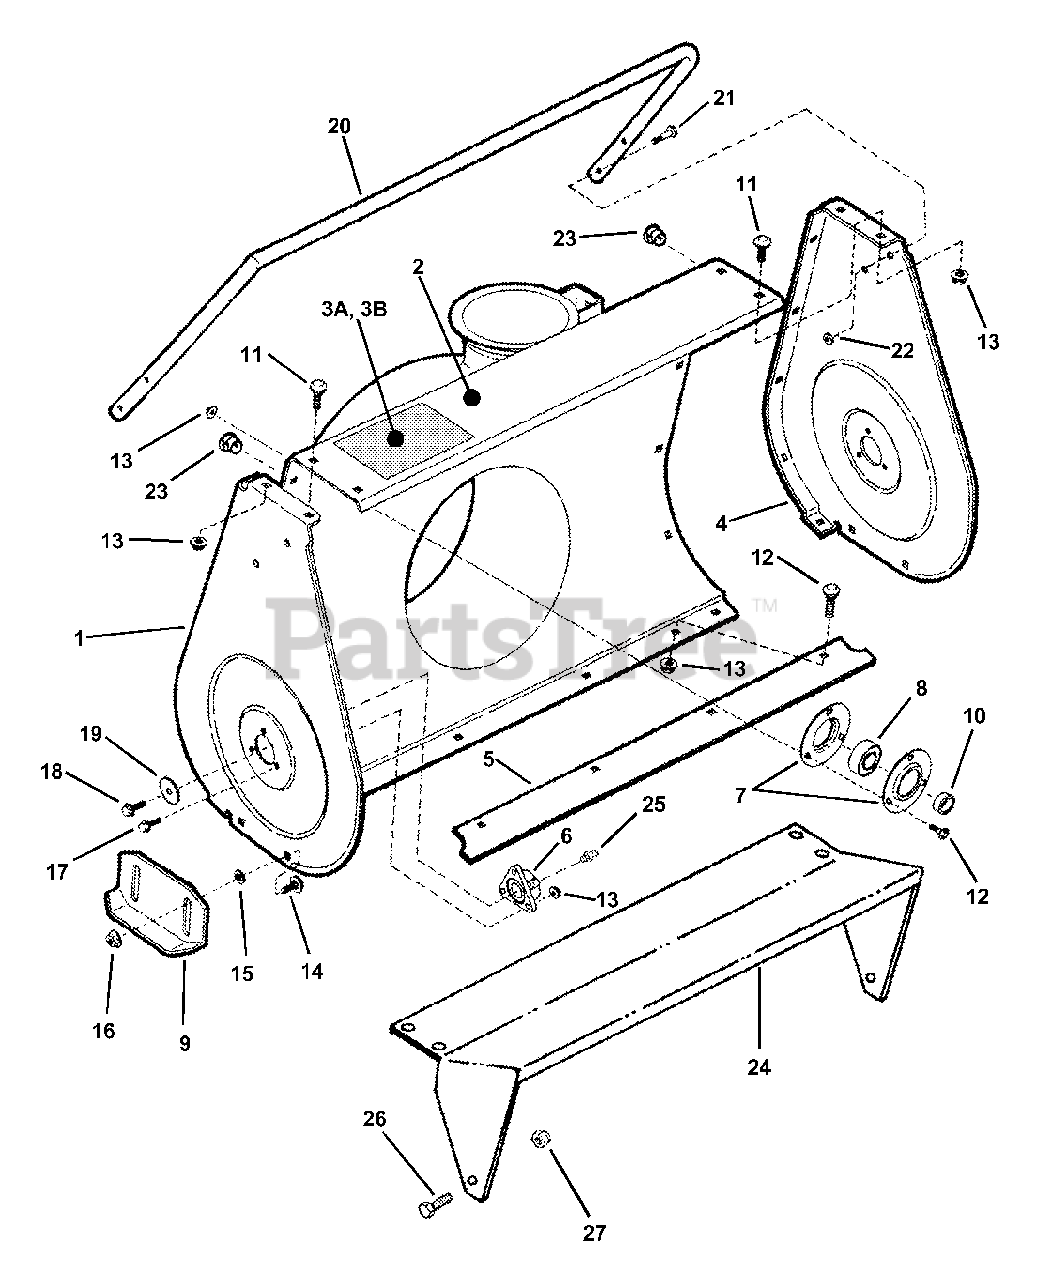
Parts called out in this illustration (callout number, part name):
1	PLATE, Right Side
2	ASSEMBLY, 22" Blower Housing (I55224 & EI55224 Models)
3A	DECAL, Foot Danger
3B	DECAL, Danger (Collector)
4	PLATE, Left Side
5	BLADE, Scraper (I55224 & EI55224 Models)
6	BEARING, Auger Shaft (I55224 & EI55224 Models)
7	HOUSING, Bearing
8	BEARING, Ball
9	SHOE, Skid
10	SPACER, 3/4 x 1/4 x 1"
11	SCREW, 1/4-20 x 5/8" Self-Tapping (Truss Head Torx)
12	BOLT, 1/4-20 x 5/8" Square Neck Carriage, Grade 5
13	NUT, 1/4-20 Hex Flange Lock
14	BOLT, 5/16-18 x 5/8" Short Neck Carriage, Grade 5
15	WASHER, 5/16 Flat
16	NUT, 5/16-18 Hex Flange Lock
17	BOLT, 1/4-20 x 3/4" Hex Flange Lock, Grade 5
18	SCREW, 5/16-18 x 5/8" Hex Washer Self-Tap
19	WASHER, 21/64" Flat
20	DRIFT-CUTTER (I55224 & EI55224 Models)
21	SCREW, 1/4-20 x 1" Hex Head Cap, Grade 5
22	NUT, 1/4-20 Hex Center Lock
23	PLUG, Dome 3/16" Diameter
24	ADAPTER, Housing (22")
25	FITTING, Lube (Press fit for .187 hole-no ball)
26	SCREW, 1/4-20 x 1/2" Hex Head Cap, Grade 5
27	NUT, 1/4-20 Hex Nyloc
